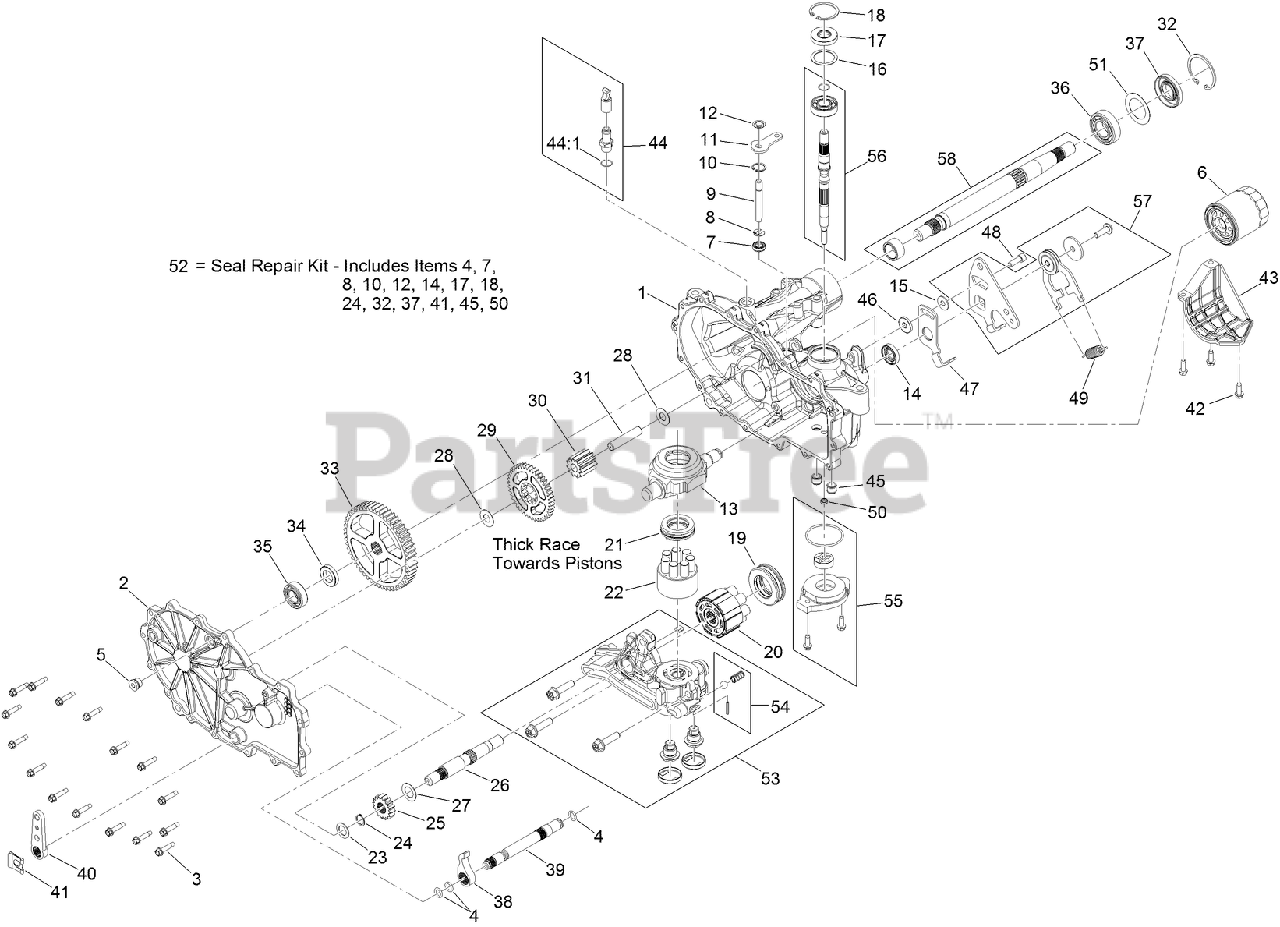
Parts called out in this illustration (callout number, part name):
1	LH MAIN HOUSING KIT
2	LH SIDE COVER KIT
3	SCREW-HHF
4	O-RING
5	PLUG-THREAD, STRAIGHT
6	ELEMENT-OIL FILTER, HYD
7	SEAL-LIP
8	RING-RETAINING, EXTERNAL
9	ROD-BYPASS
10	RING-RETAINING, INTERNAL
11	Arm-Bypass
12	RING-RETAINING, EXTERNAL
13	SWASHPLATE-TRUNNION
14	SEAL-LIP
15	WASHER
16	SPACER
17	SEAL-LIP
18	RING-RETAINING
19	Bearing-Thrust
20	MOTOR CYLINDER BLOCK KIT
21	BEARING-THRUST
22	PUMP BLOCK ASM
23	WASHER-FLAT
24	RING-RETAINING
25	GEAR-16T
26	SHAFT-MOTOR
27	WASHER
28	WASHER
29	GEAR-43T
30	GEAR-11T
31	PIN-JACKSHAFT
32	RING-RETAINING
33	GEAR-54T
34	SPACER
35	BEARING-BALL
36	BEARING-BALL
38	PAWL-BRAKE
39	SHAFT-BRAKE, INBOARD
40	HANDLE-BRAKE
41	RING-RETAINING, EXT
43	GUARD-FILTER, RH
44	ADAPTER-STRAIGHT
44:1	O-RING
45	TUBE-CONNECTING
46	SPACER
47	ARM-NEUTRAL, LEFT
48	Screw-Sh
49	SPRING-EXTENSION
50	SEAL-GEROTOR
51	SPACER
52	SEAL KIT
53	LH CENTER SECTION CHARGE KIT
54	CHARGE RELIEF KIT
55	CHARGE KIT
56	INPUT SHAFT KIT
57	CONTROL ARM KIT
58	AXLE SHAFT KIT
